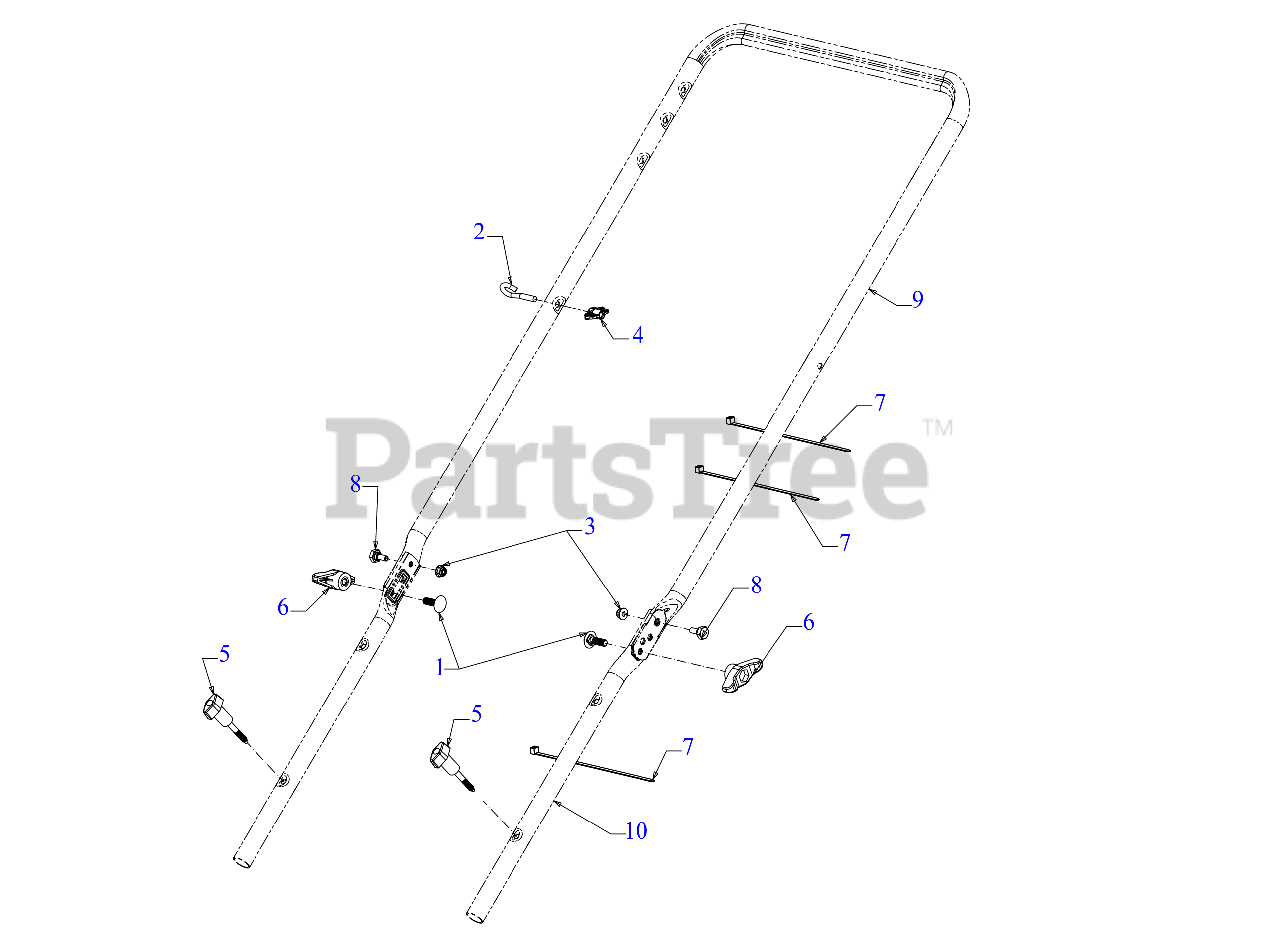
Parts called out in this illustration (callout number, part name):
1	SCREW 5/16-18 x 1.00 GR5
2	EYEBOLT 1/4-20
3	FLANGE LOCK NUT
4	HANDLE KNOB
5	WING KNOB 1/4-20
6	WING KNOB 5/16-18
7	7" CABLE TIE
8	SHOULDER SCREW
10	LOWER HANDLE
